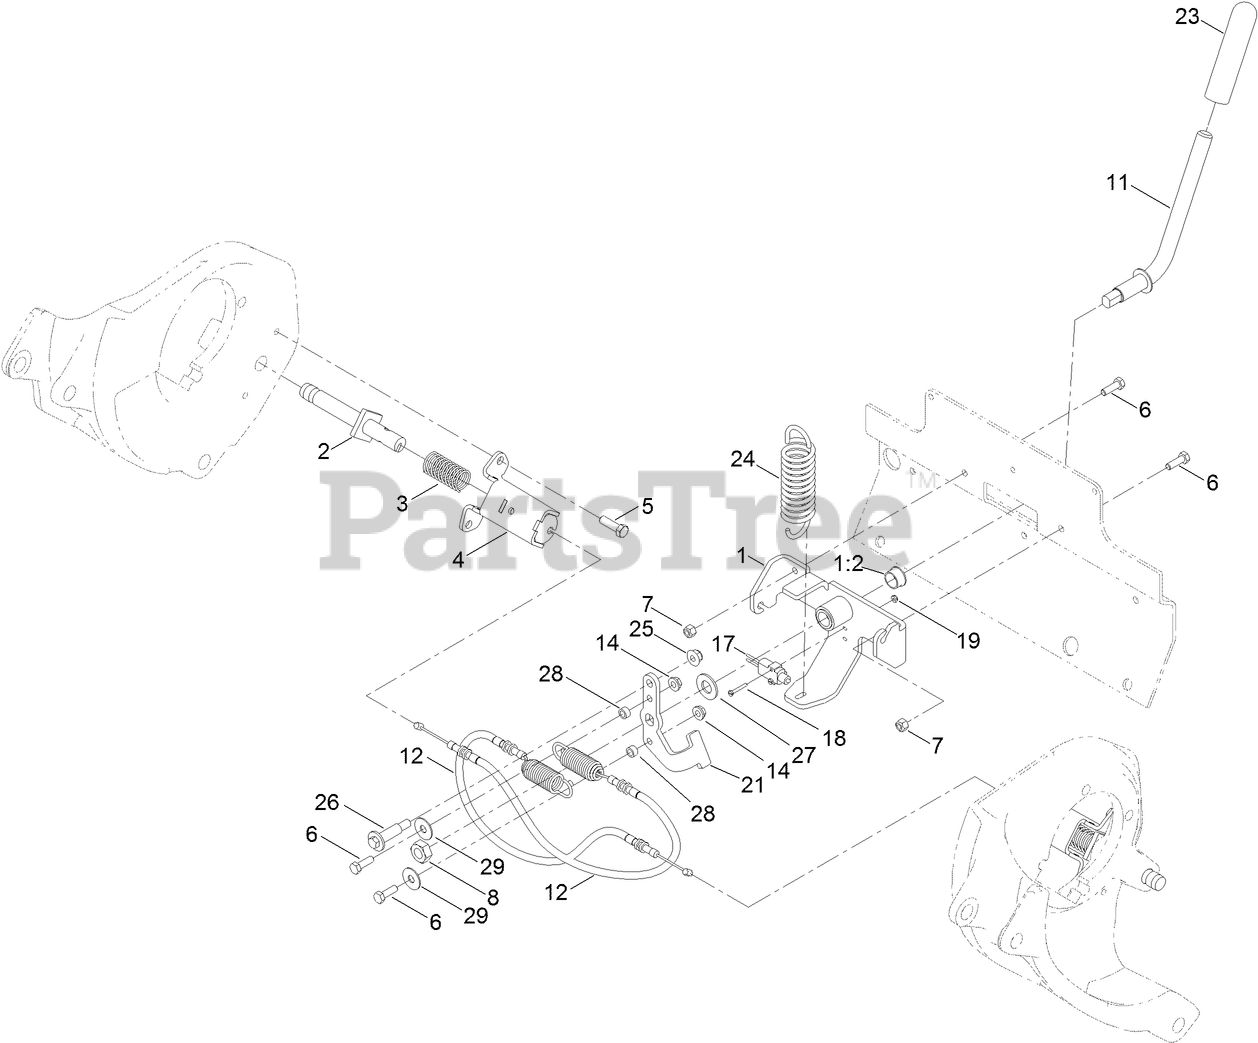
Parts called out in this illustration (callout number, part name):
1	BRACKET-BRAKE
1:2	BEARING-FLANGE
2	ROD-BRAKE
3	SPRING-COMPRESSION
4	MOUNT-BRAKE
5	SCREW-HH
6	SCREW-HH
7	NUT-LOCK, NI
8	NUT-LOCK, NI
11	LEVER-BRAKE
12	CABLE-BRAKE
14	NUT-HF
17	SWITCH
18	SCREW
19	NUT-HEX
21	PLATE-BRAKE LINKAGE
23	GRIP-HANDLE
24	SPRING-EXT
25	NUT-HF, NI
26	BOLT-SHOULDER
27	WASHER-FLAT
28	SPACER-PIVOT, TILT
29	WASHER
